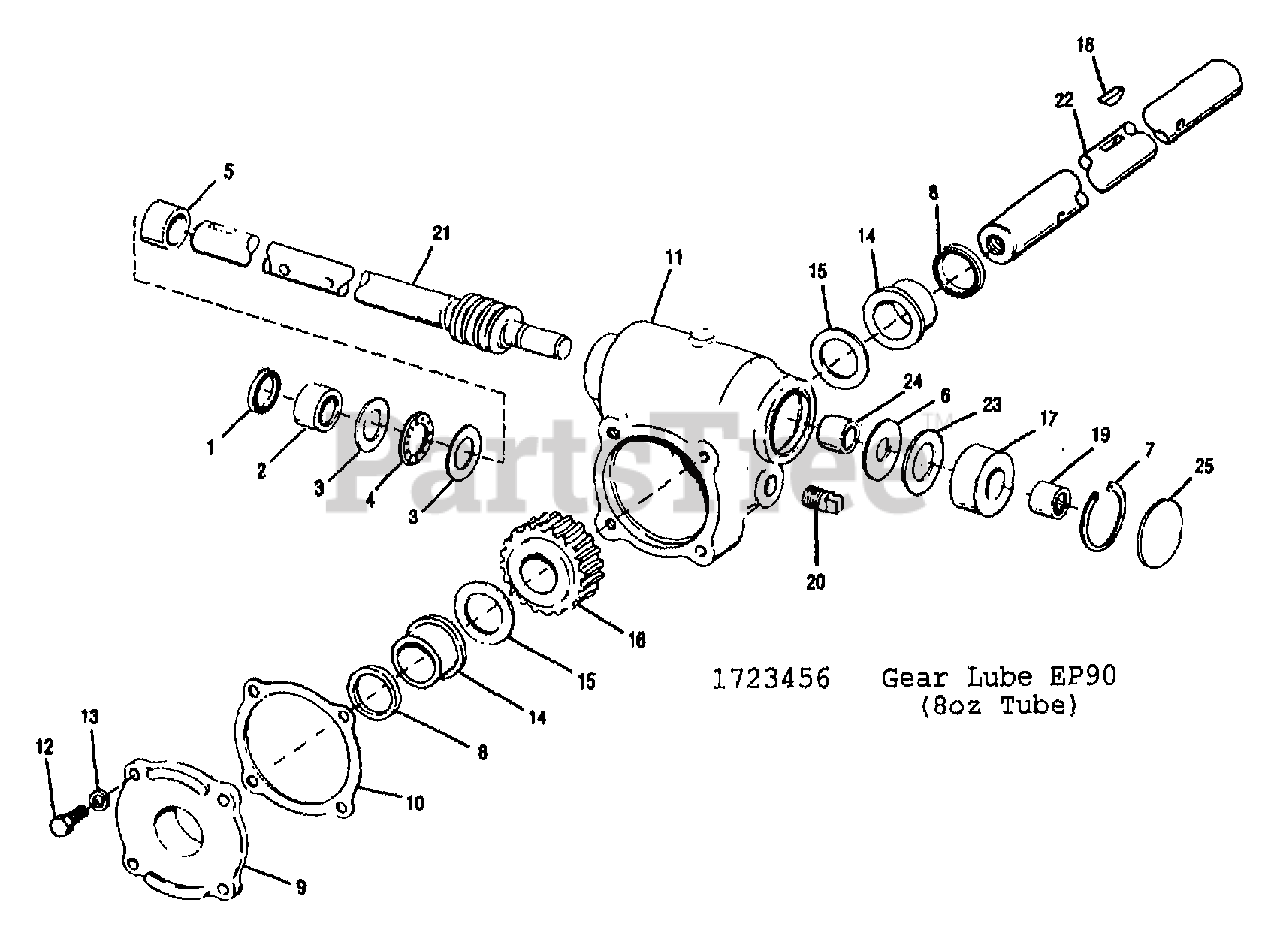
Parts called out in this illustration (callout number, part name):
1	SEAL-OIL 3/4 DIAMETER
2	BEARING-NEEDLE
3	RACE-THRUST
4	BEARING-THRUST
5	SPACER-1.0X.752X.302
6	WASHER
7	RING-RETAINING INTERNAL
8	SEAL-OIL
9	COVER-FLANGED
10	GASKET-COVER
11	CASE ONLY-GEAR
12	SCR-HH 1/4-20X.625 G5 ZP
13	WASHER-LK .25 ZP
14	BUSHING-FLANGE
15	RACE-THRUST
16	GEAR-WORM 20 TEETH
17	SPACER-1.503X.749X.56
18	KEY-WOODRUFF .25X.875
19	BEARING-NEEDLE
20	PLUG-SQ HEAD 1/4-18 NPT
21	ASSM-SHAFT IMPELLER 21"
22	SHAFT-AUGER
23	RACE-THRUST
24	SPACER-.812X.566X.448
25	PLUG-EXPANSION
